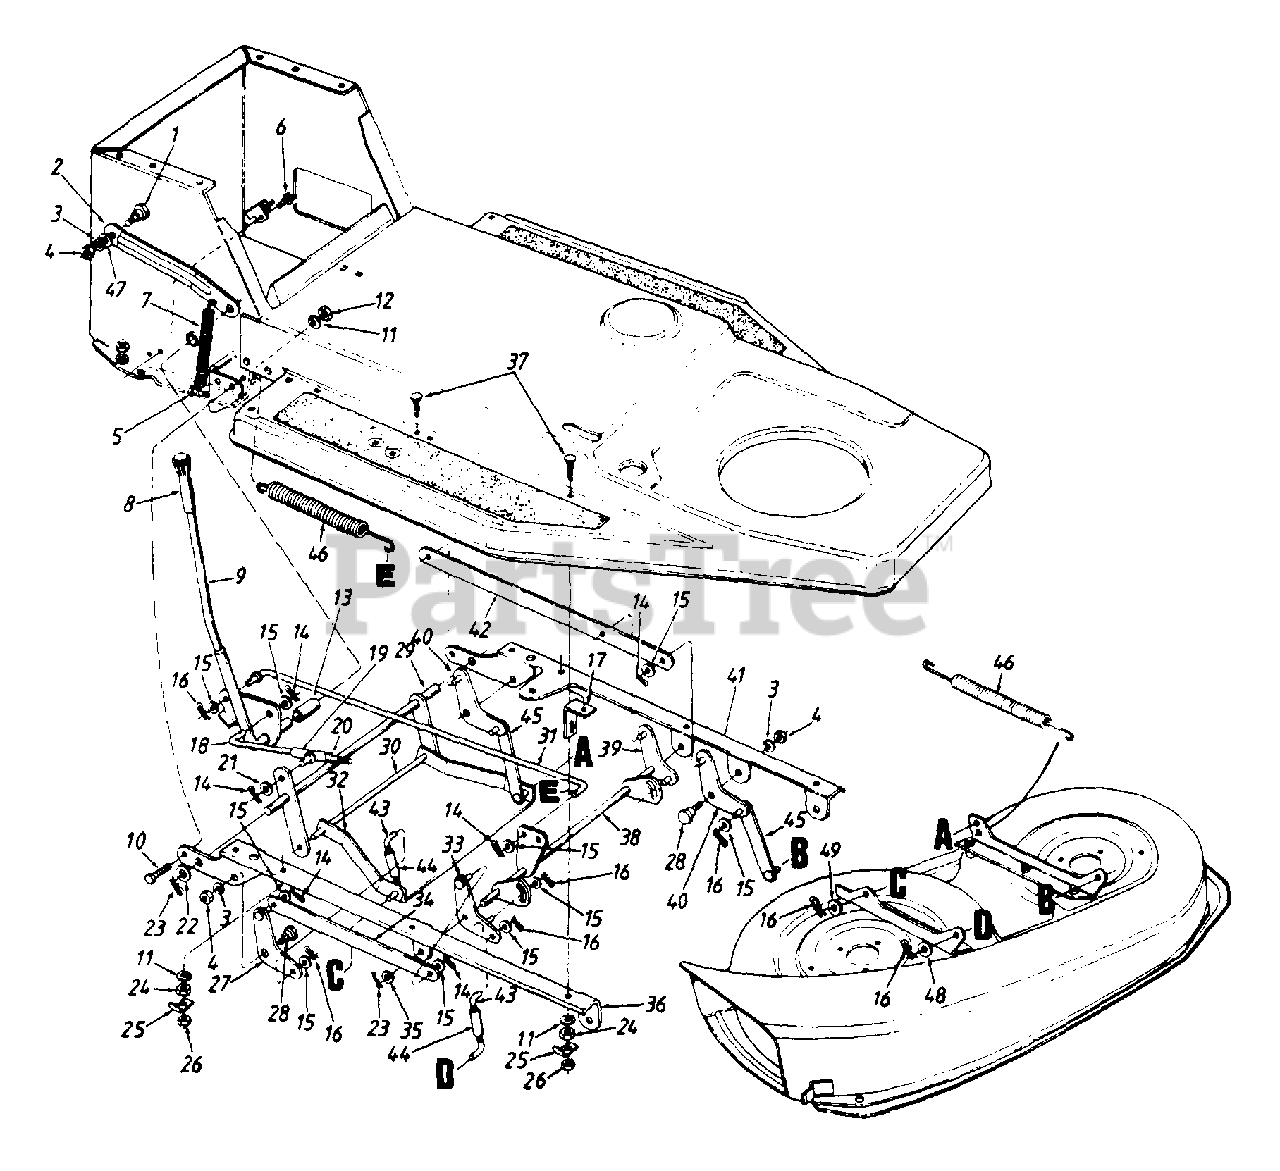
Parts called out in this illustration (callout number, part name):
1	Shld. Bolt .5" Dia. x .34" Lg.
4	Hex Nut 3/8-16 Thd.
5	Hex Bolt 1/4-28 x 1.25" Lg.
6	Hex Wash. Hd. TT-Tap Scr. 1/4-20 x .5" Lg.
7	Ext. Spring
9	Deck Lift Handle Ass'y.
10	Hex Wash. TT-Tap Scr. 5/16-18 x .62" Lg.
11	L-Wash. 5/16" I.D.
12	Hex Nut 5/16-18 Thd.
13	Spacer 5/8" I.D. x .78"
14	Cot-Pin 3/32" Dia. x .75" Lg.
15	Fl-Wash..406" I.D. x .75" O.D.
16	Internal Cot-Pin 8/16" Dia.
19	Pivot Sleeve Ass'y.
20	Hex L-Nut 3/8-16 Thd.
21	Thrust Washer .382" I.D.
22	Fl-Wash..635" I.D. x .93" O.D.
23	Cot-Pin 1/8 Dia. x 1.25" Lg.
24	Hex Nut 5/16-24 Thd.
25	Harness Retainer
26	Hex Cent. L-Nut 5/16-24 Thd.
27	Deck Pivot Brkt. Ass'y.- R.H. Rear
28	Shld. Bolt .625" Dia. x .170" Lg.
31	Deck Lift Rod
32	Deck Stabilizer Brkt.
44	Adj. Lift Link Ass'y.
45	Deck Lift Link Ass'y.
46	Deck Spring 10.33" Lg.
47	Fl-Wash..531" I.D. x .94"
48	Fl-Wash..406" I.D. x.75"
49	Fl-Wash. 3/8" I.D.
